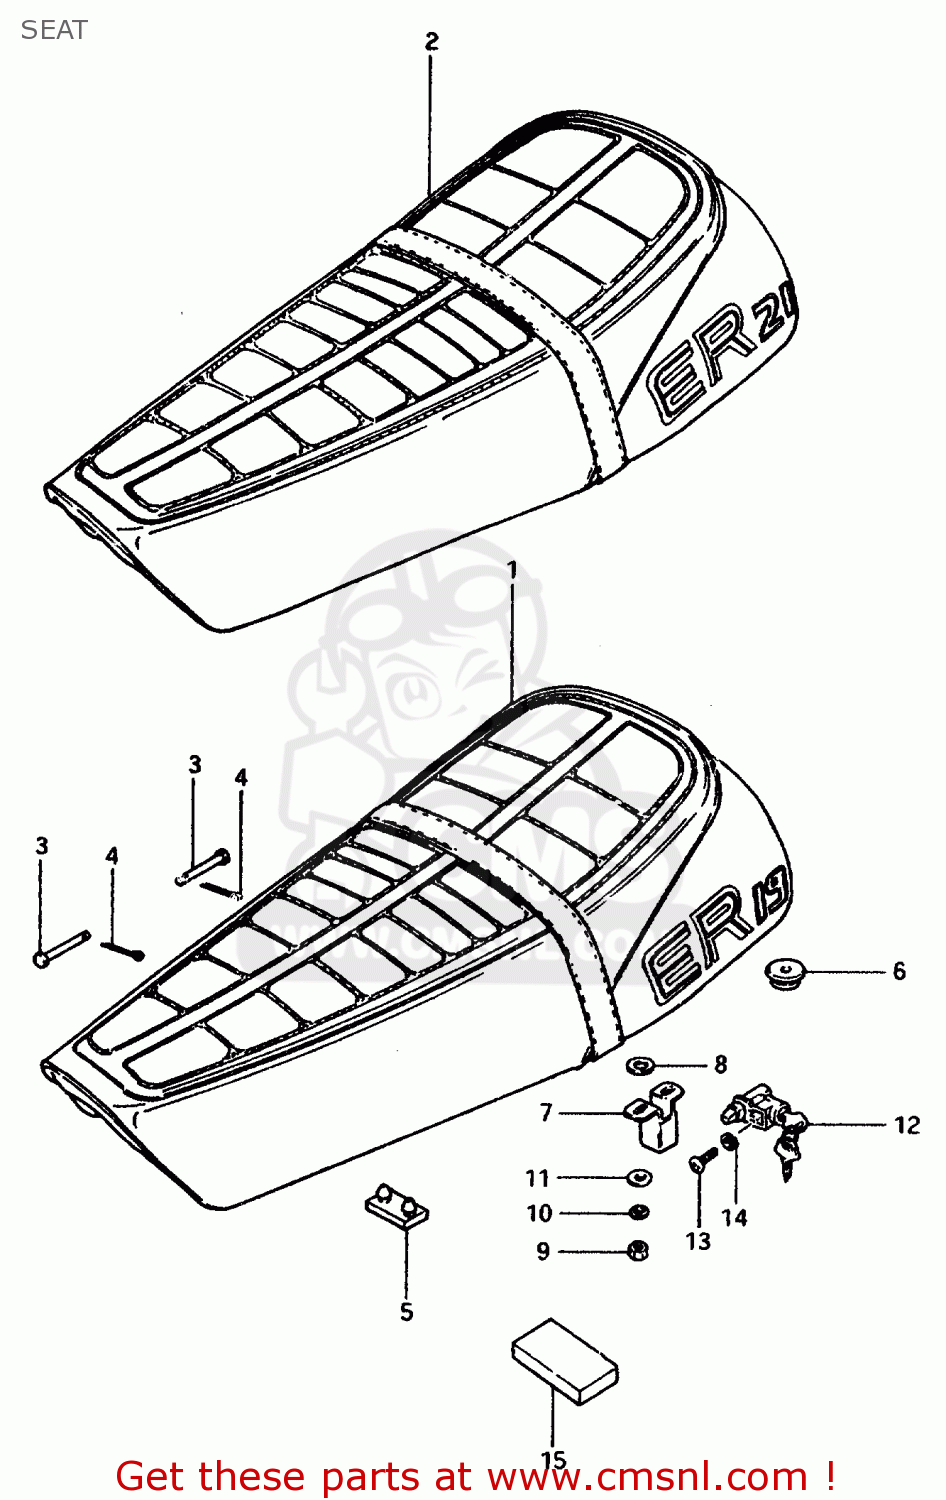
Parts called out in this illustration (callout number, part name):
1	SEAT ASSY (BLACK)
2	SEAT ASSY (BLACK)
3	PIN
4	PIN
5	CUSHION
6	CUSHION
7	PLATE,CLAMP GUIDE
8	WASHER(8.5X18X1)
9	NUT
10	LOCK WASHER
11	WASHER
12	LOCK ASSY,SEAT
13	SCREW
14	LOCK WASHER
15	CUSHION(30X60X10)
16	CARRIER,SPORT
